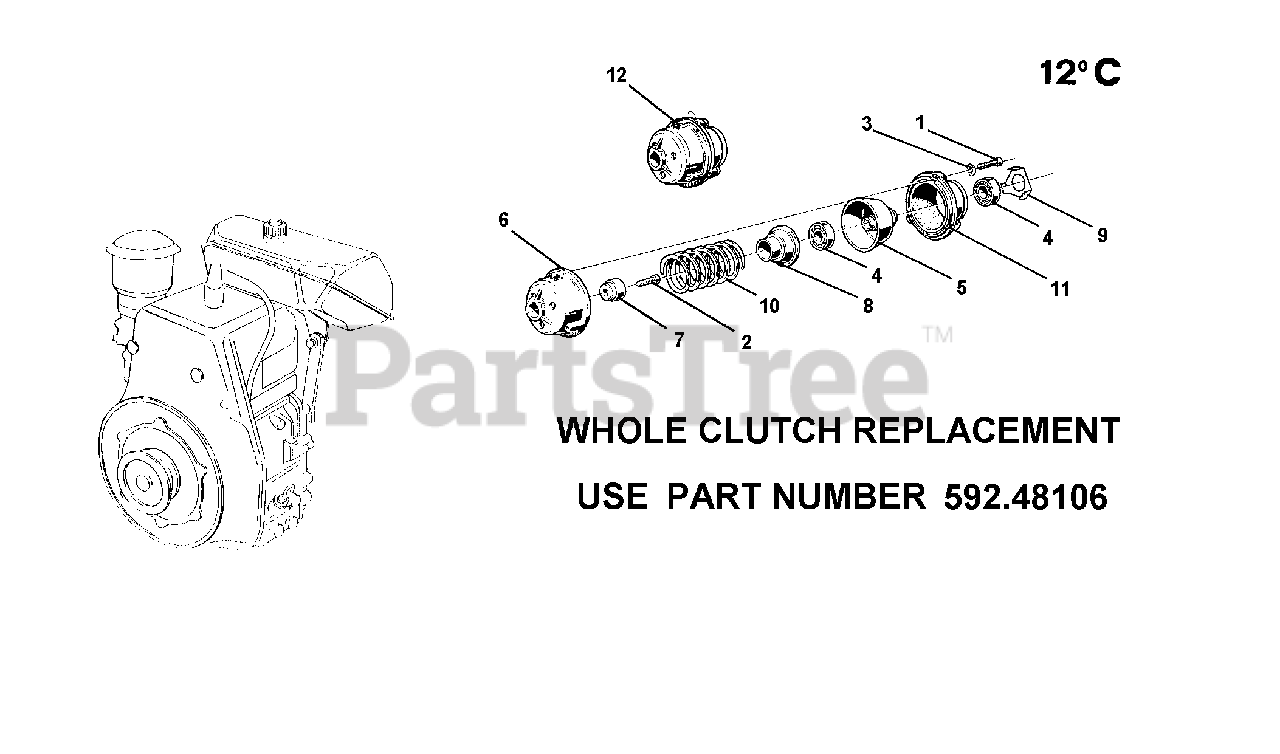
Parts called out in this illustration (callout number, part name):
1	SCREW M6 X 35
2	SCREW TE CE M8 X 25
3	WASHER, LOCK 6.4
4	BEARING 17 X 40 X 12 6203 2RS
5	CONE, CLUTCH
6	BELL, CLUTCH SPRING AL 290
8	BUSH, SPRING HOLDER
9	BEARING PLATE
10	SPRING CLUTCH
11	CLUTCH RING
12	CLUTCH, REPLACED BY 592.48106
